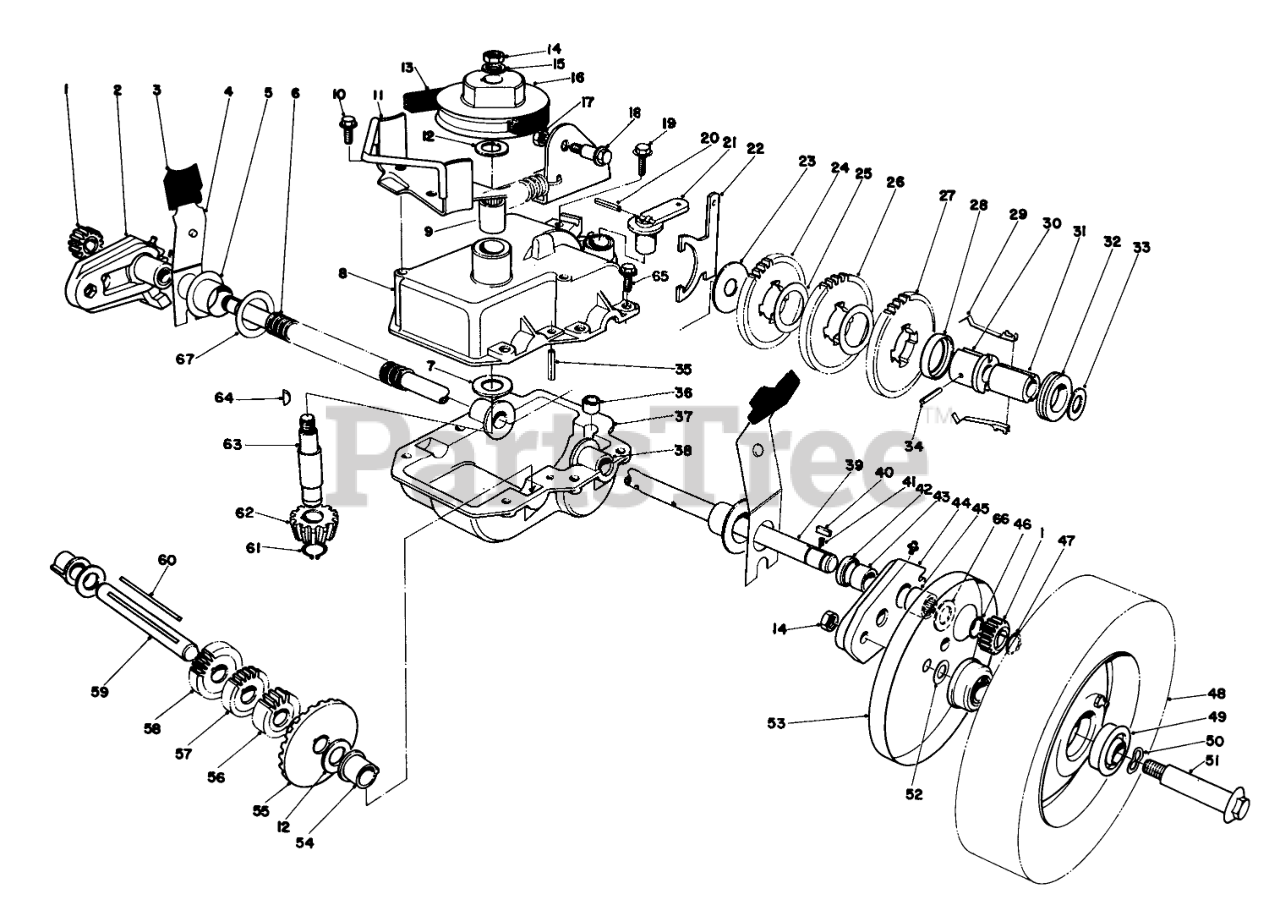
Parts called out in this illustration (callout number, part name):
1	GEAR-PINION
2	Pivot Arm R.H. (Incl. Ref. #42 43 & 45)
3	KNOB-ARM
4	Spring Arm
5	CAP-END
6	CONDUIT-CONVOLUTED, SPLIT
7	Thrust Washer
8	Case-Upper
9	Bearing
10	Hex Head Screw
11	Belt Guide Bracket
12	Washer
13	V-BELT
14	Nut
15	Washer
16	PULLEY
18	SHOULDER BOLT
19	SCREW-HWHTF
20	PIN-COIL
21	LEVER-SHIFT
22	Shift Yoke
23	WASHER
24	Gear-38T
25	Washer
26	Gear-40 Tooth
27	GEAR-42T
28	KEY RETAINER
29	Key
30	Body-Sleeve
31	SLEEVE
32	COLLAR-SHIFT
33	Washer
34	PIN-SPRING
35	ROLL PIN 3/16 X 1 IN
36	BUSHING-YOKE
37	LOWER GEAR CASE CAST
38	Bushing-Output Shaft
39	Output Shaft
40	KEY RECTANGULAR
41	SPRING-COMPRESSION
42	Seal
43	0 Bushing
44	Pivot Arm L.H. (Incl. Ref. #42, 43 & 45)
45	Needle Baring
46	RING-EXT GRIP
47	RING-RETAINING
48	WHEEL ASM
49	BEARING-BALL
50	SPRING WASHER
51	Wheel Bolt
52	WASHER
53	Cover-Wheel
54	Botching Shaft
55	BEVEL GEAR
56	14 T GEAR
57	16 T GEAR
58	GEAR-18T
59	Sort Shaft
60	Key Square
61	RING-RETAINING
62	PINION-BEVEL
63	INPUT SHAFT
64	KEY-WOODRUFF
65	SCREW-HWH, THREAD ROLL
66	Washer
67	Washer
